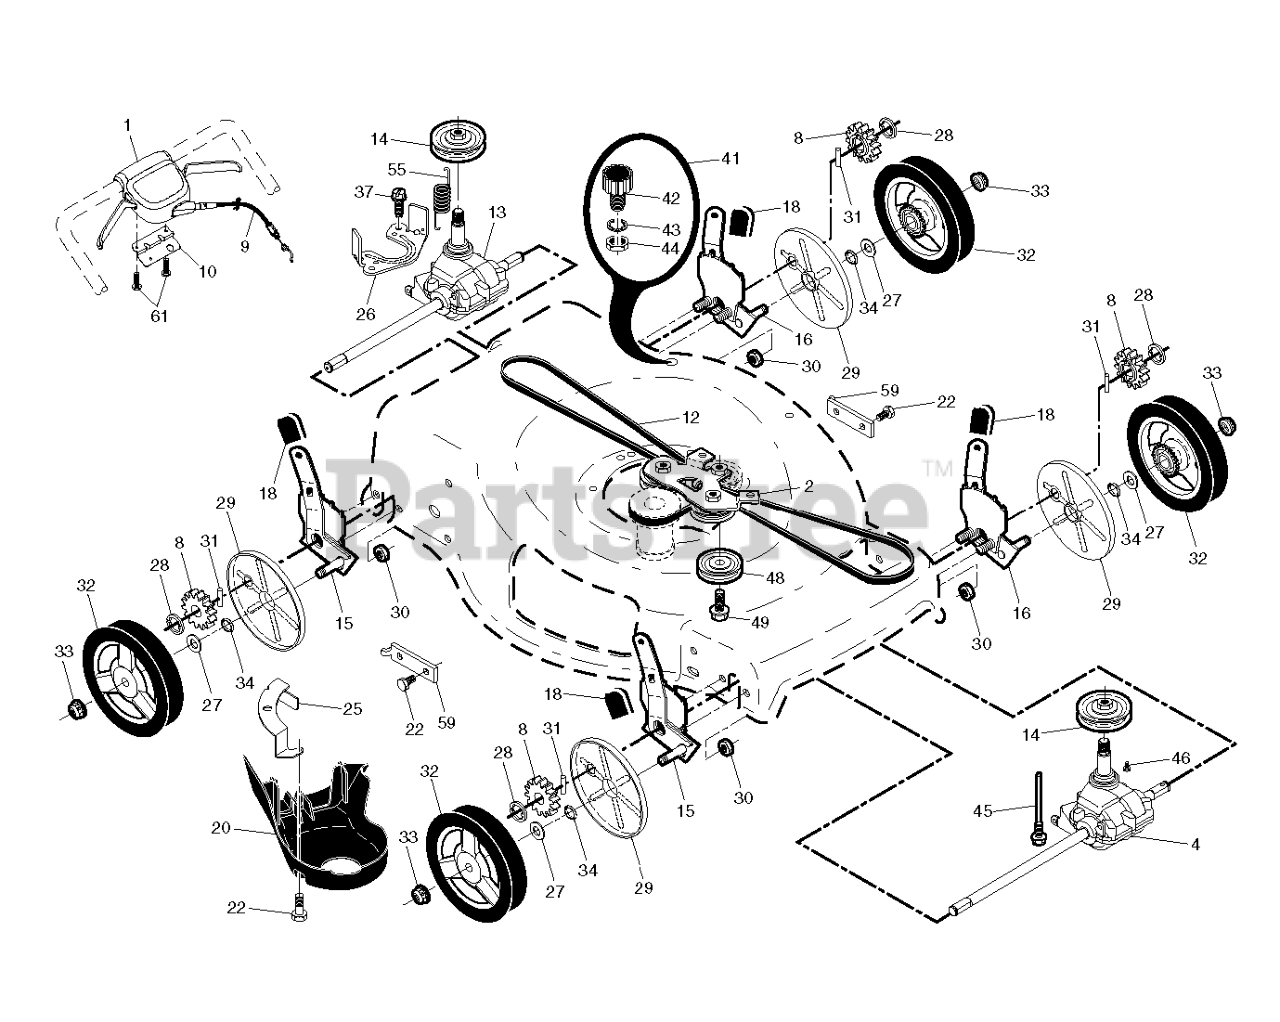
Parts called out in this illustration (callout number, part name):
1	CONTROL.AWD.DT.BS
2	BRACKET.ASM.AWD.BZP.BLACK
4	TRANSMISSION.22+.AWD.FRT
8	PINIION.14.TOOTH.RGD
9	CABLE.DRIVE.RWD.WALK.
10	BRACKET DUAL TRIGGER CONTROL
12	BELT V3L 64.10 CLUTCHING COVER
13	TRANSMISSION.22+AWD.WALK.MOWER
14	PULLEY.DRIVE.SM.AWD/RWD
15	ADJUSTER.ASM.22+FGD.RF /AWD RT
16	ADJUSTER.ASM.22+FGD.LF /AWD LT
18	SELECTOR KNOB
20	COVER.REAR.DRIVE.22+2013
22	BOLT.5/16HEX.WHS.HD
25	BRACKET.DRIVE.COVER.RGD.BZP
26	BRACKET.TRAN.BELTKEEPER.22+RGD
27	WASHER FLUT
28	E-RING 7/16 RE
29	COVER.DUST.WHEEL.INNER.WALK
30	NUT.FLANGE.1-4-20-SERR
31	PAWL, DRIVE
32	WHEEL.8".AWD.3SP.EXT.DR.GREY
33	NUT.HEX.FLANGE.3/8-16.LO(3 2)
34	O-RING..070X.487.NEOPRENE
41	KIT.WASH-OUT.PORT
42	FITTING, HOSE, WATER WASHOUT
43	WASHER.LOCK.INTERNAL.TOOTH
44	LOCKNUT.HEX.WITH.O-RING
45	SCREW.HI-LO.5/16-14 X 4.10
46	SCREW.HI-LO. 5/16 X 1.00
48	PULLEY.ASM.22+ AWD
55	SPRING.RETURN.AUTO.
59	BRACKET.SUPPORT.22+RWGD.BZP
61	SCREW, PHILLIPS HEAD 10 X 5/8
